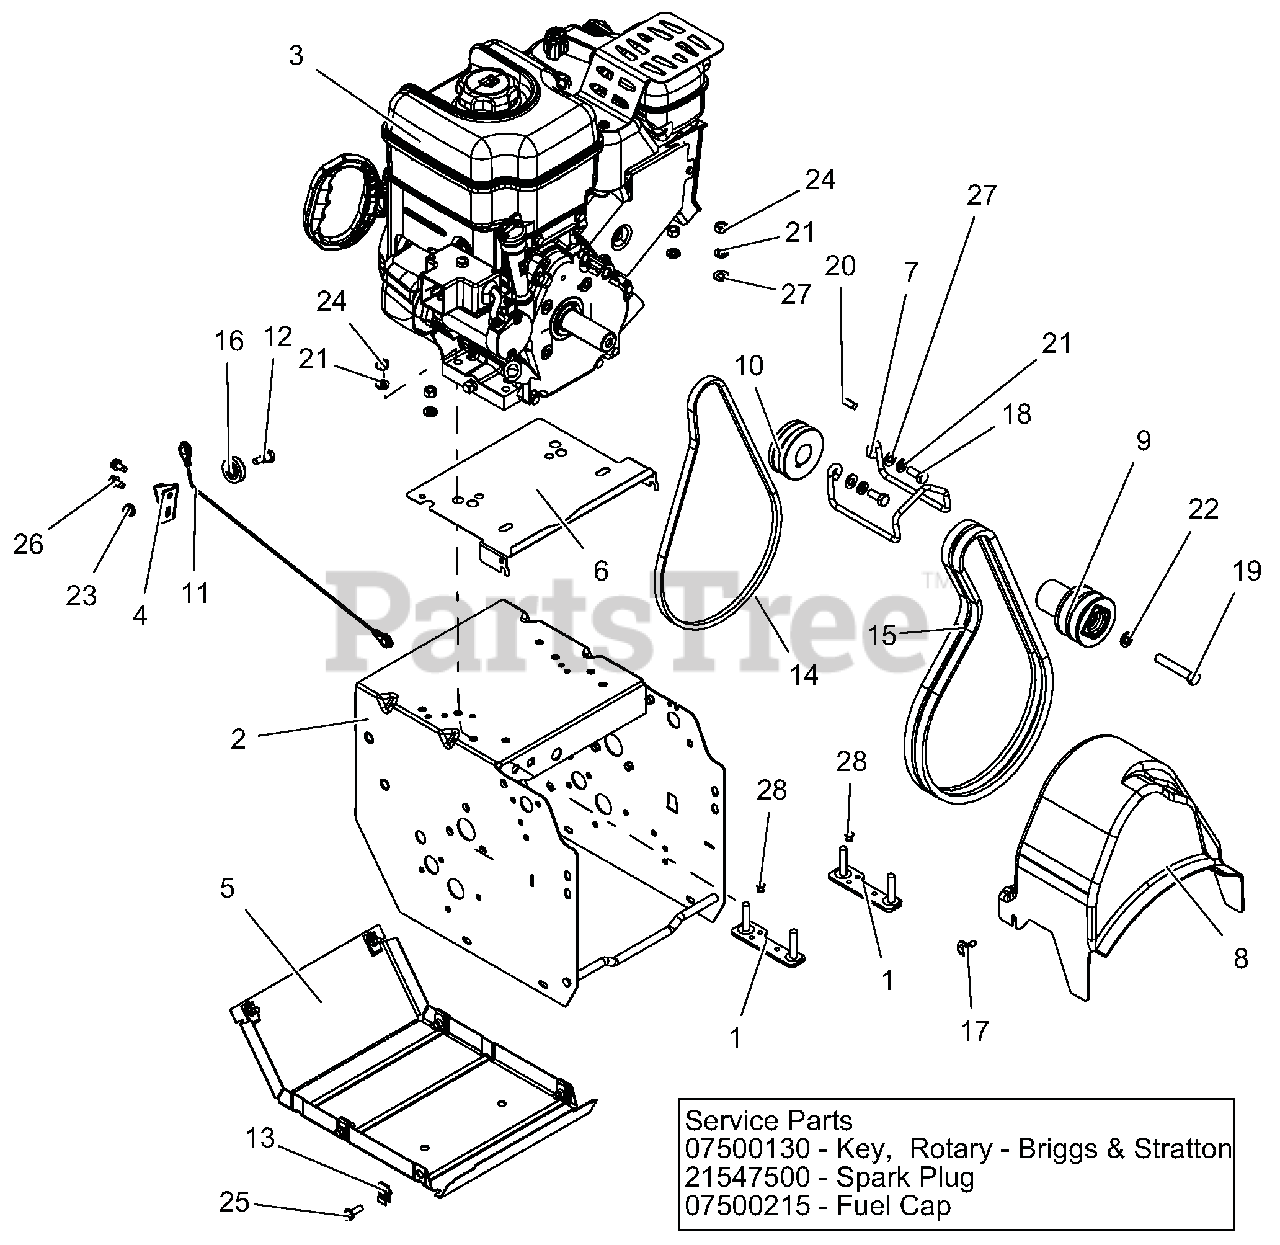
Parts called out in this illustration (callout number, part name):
1	STRAP, ENGINE BOLT-WELDMENT
2	FRAME, 920/921
3	ENGINE, BRIGGS SNOW 1150, 240V
4	BRACKET, CABLE PULLEY
5	COVER, BOTTOM
6	BAFFLE,ENGINE,SMALL BLOCK
7	FINGER, BELT
8	BELT COVER
9	SHEAVE,ATTACHMENT 2-GRV
10	SHEAVE DRIVE
11	CABLE, LOWER TRACTION (DELUXE)
12	BOLT, SHLDR-.375X.375X.25-20
13	NUT-RTNR .25-20X.56
14	V-BELT, 3L-WRAPPED
15	V-BELT, HA-RAW EDGE (SET)
16	PULLEY, CABLE
17	SCR-TAP .25-20X.5 CAPTIVE
18	BLT-HEX .31-24X.75 YWZC GR5
19	BLT-HEX .38-24X2.25 YWZC GR5
20	KEY-SQ .25X.625X.25 SAE 8630
21	WSHR-LK .312X.097 HVY YWZC
22	@WSHR-LK .38X.094 REG YWZC
23	@NUT-LK-CTR-FLG .25-20 YWZC
24	@NUT-HEX .31-18 YWZC
25	BLT-HEX .25-20X.75 HWH YZ GR5
26	SCR-TAP .25-20X.50 HWH TR YWZ
27	@WSHR-FL-STL.344X.688X.065YWZC
28	RVT-POP .187 YZ
